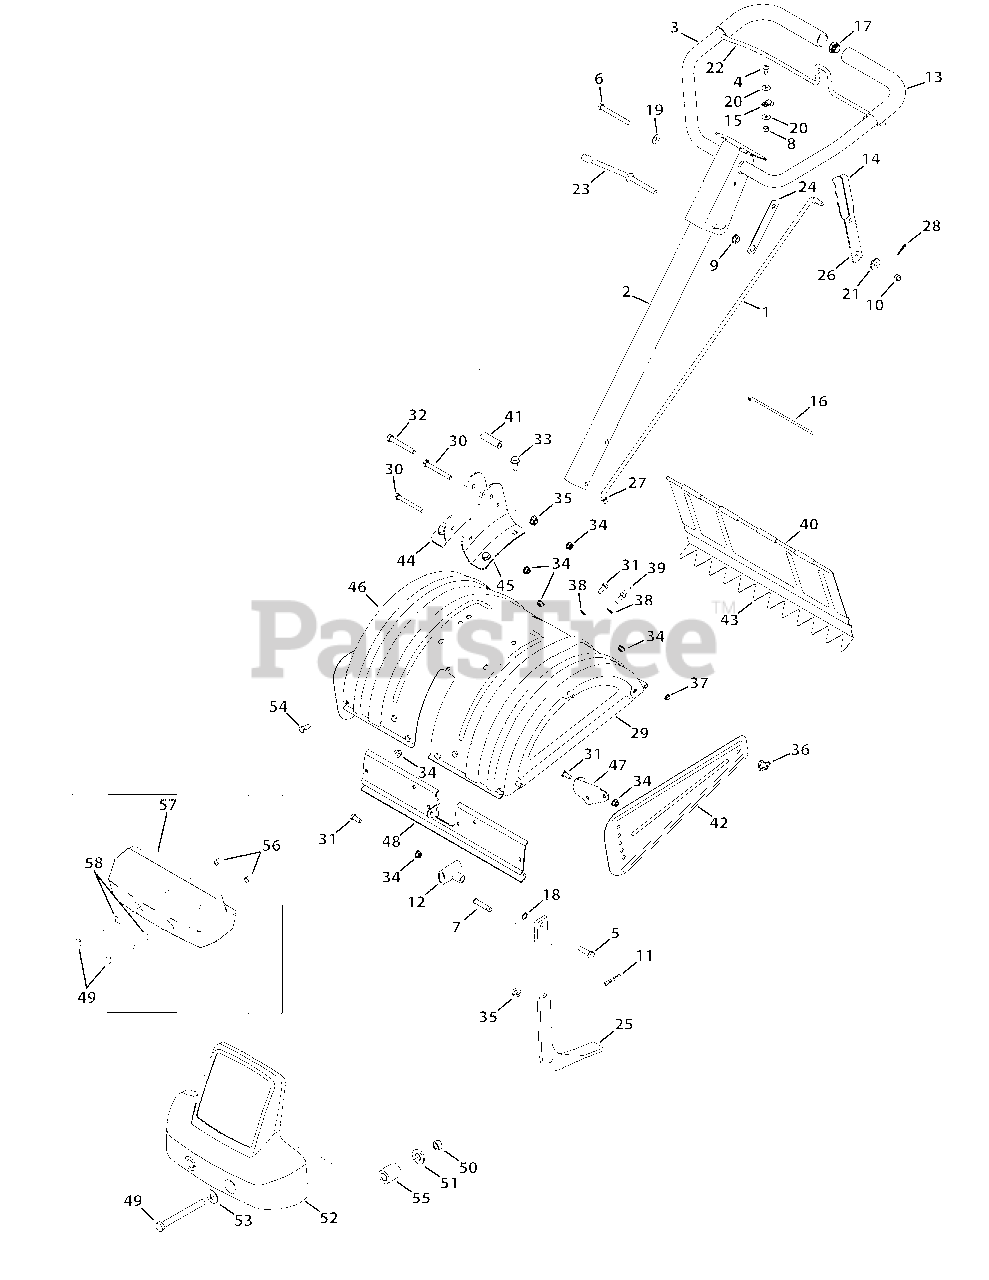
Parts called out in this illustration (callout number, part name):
1	Shaft Rod
2	Lower Handle Tube Assembly
3	Upper Handle Assembly
4	Screw, 1/4-20 x 0.625
5	Hex Head Screw, 3/8-16x1.25
6	Hex Head Screw, 5/16-18 x 3.25
7	Clevis Pin, .375 X 1.75
8	Hexlock Nut, 1/4-20
9	Flangelock Nut, 3/8-24
10	Hexlock Nut, 5/16-18
11	Cotter Pin, .125 X 1.75 INTERNAL
12	Small Tee Knob
13	Foam Grip, .970 x 11.0
14	Grip, .1875 x 1.00
15	Battery Clamp, 5/16
16	Cable Tie, 8.5 LG
17	End Plug
18	Washer, Flat, .385 x .620 x .033
19	Washer, Bell, .340 x .872 x .060
20	Washer, Flat, .260 x .720 x .060
21	Spacer, Shoulder, .50 x .190 x .360 LG
22	Clutch Bail
23	Handle Adjustment Crank
24	Hex Nut Retainer Bracket
25	Tiller Depth Control
26	Shaft Rod Lever
27	Washer, Rubber, .33 ID x .87 OD x .125
28	Cotter Pin, .072 x 1.12 LG
29	End Cover Assembly
30	Hex Head Screw, 5/16-18 x 2.75
31	Hex Head Screw, 5/16-18 x .75
32	Hex Head Screw, 3/8-16 x 2.75
33	Hex Head Flange, 3/8-16 x .875
34	Flangelock Nut, 5/16-18
35	Flangelock Nut, 3/8-16
36	Wing Nut, 5/16-18 W/ Bell Washer
37	Speed Nut Cap, 1/4 ROD
38	Washer, Flat, .344 x .62 x .033
39	Screw, Hex, 5/16-18 x .75
40	Tiller Flap Rod
41	Spacer, .322 x .625 x 2.00
42	Side Shield
43	Rear Tine Shield
44	RH Handle Mount Bracket
45	LH Handle Mount Bracket
47	FRT Tine Shield Bracket
48	FRT Tine Shield Spacer Bracket
49	Hex Head Screw, 1/2-13 x 5.00
49	Hex Head Screw, 1/2-13 x 5.50
50	Hex Nut, 1/2-13
50	Hex Nut, 1/2-20
51	Washer, 1/2 x 1.25 x .10
52	Counterweight
53	Washer, Flat, 1/2 x 1.25 x .100
54	Hex Head Screw, 5/16-18 x 1.00
55	Hub, .636 ID x 1.00 OD x .94
56	Flange Lock Nut, 1/2-13
57	Counterweight, 40 lbs.
58	Flat Washer
